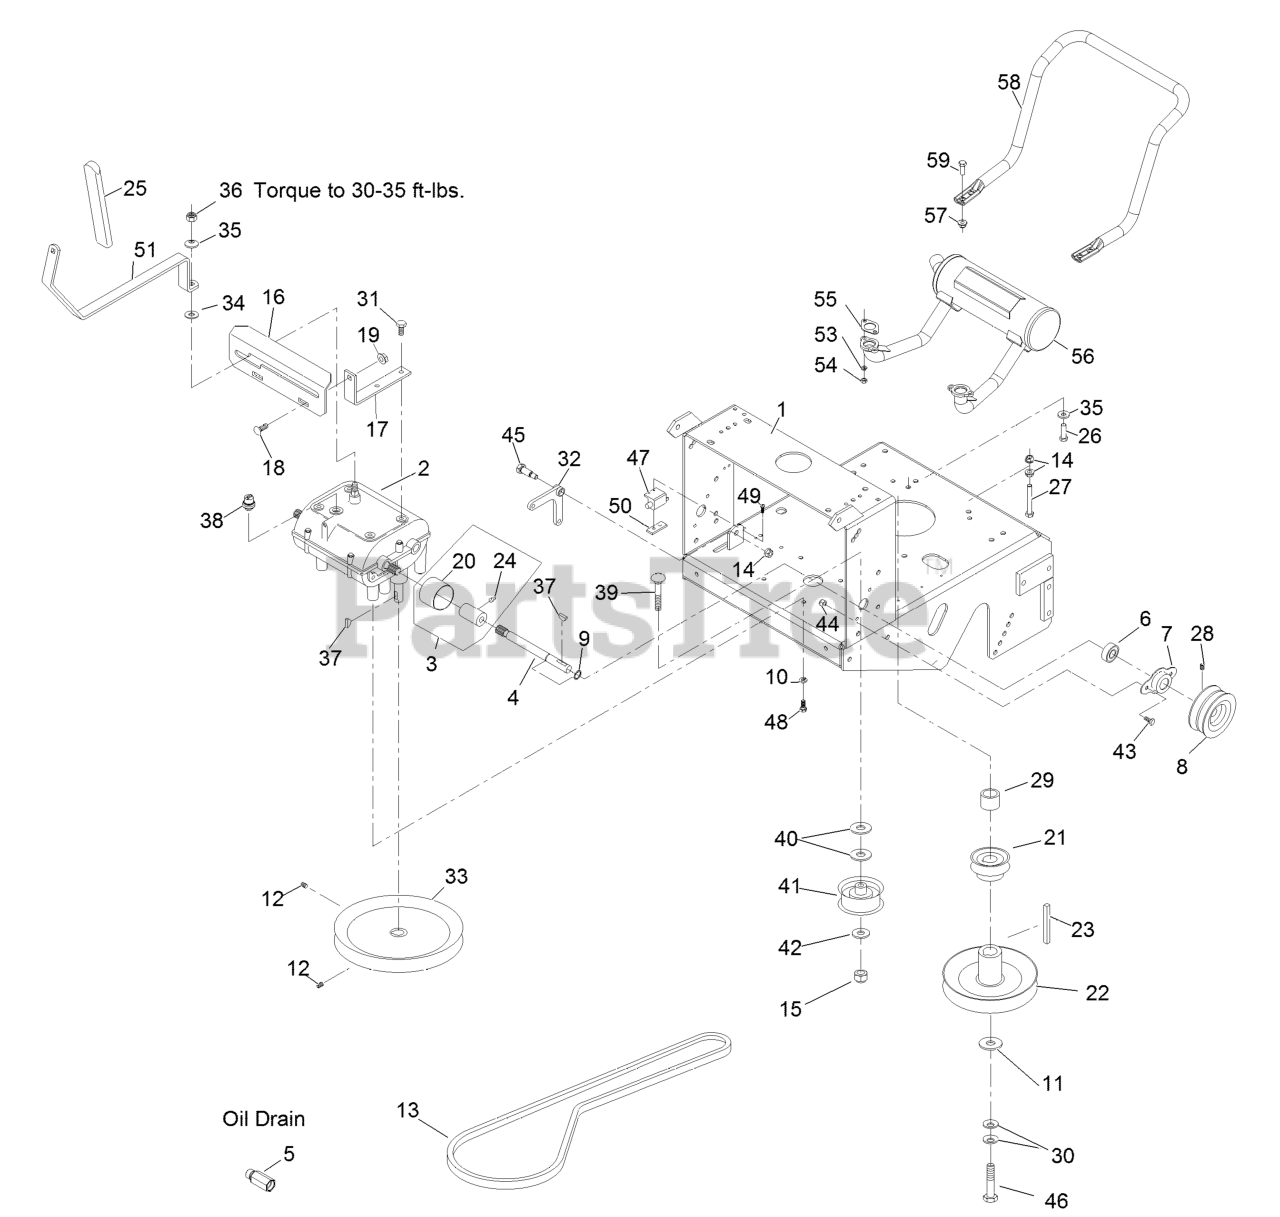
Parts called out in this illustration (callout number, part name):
1	ASM, METRO ENGINE DECK W/
3	ASM,COUPLER/ZERK
4	SHAFT-TRANSMISSION
5	ADAPTER
6	BEARING-SHAFT
7	FLANGE-OUTPUT
8	SHEAVE-TRANSMISSION
9	RING-RETAINING
10	WASHER-LOCK
12	SCREW-HSH
13	BELT,TRANS DRIVE
14	NUT-HHF, WHIZ
15	NUT-LOCK, NI
16	PLATE,SHIFTER W/DECAL
17	BRACKET-PLATE, SHIFT
18	BOLT-CARR
19	NUT-HF, NI
20	GUARD-COUPLER
21	SHEAVE-TRANSMISSION
24	FITTING-GREASE
25	GRIP,FOAM
26	SCREW-HH
27	SCREW-HH
28	SETSCREW
29	SPACER-CLUTCH
30	WASHER-SPRING
31	SCREW-THD ROLL, HWH
32	BELLCRANK
33	SHEAVE-TRANSMISSION
35	WASHER-BELLEVILLE
36	NUT-LOCK
37	KEY-WOODRUFF
38	SWITCH-START, NEUTRAL
39	SCREW-HH
40	WASHER-FLAT
42	WASHER-FLAT
43	SCREW-HH
44	NUT-LOCK, NI
45	BOLT-SHOULDER
46	SCREW-HH
47	SWITCH-OPEN, NORMALLY
48	SCREW-HH
49	SCREW-PPH
50	PLATE-TAPPED
51	ASM,SHIFT LEVER
53	WASHER-LOCK
55	GASKET-EXHAUST
56	MUFFLER-HORIZONTAL
57	NUT-HF, NI
58	GUARD-MUFFLER
59	SCREW-HH
